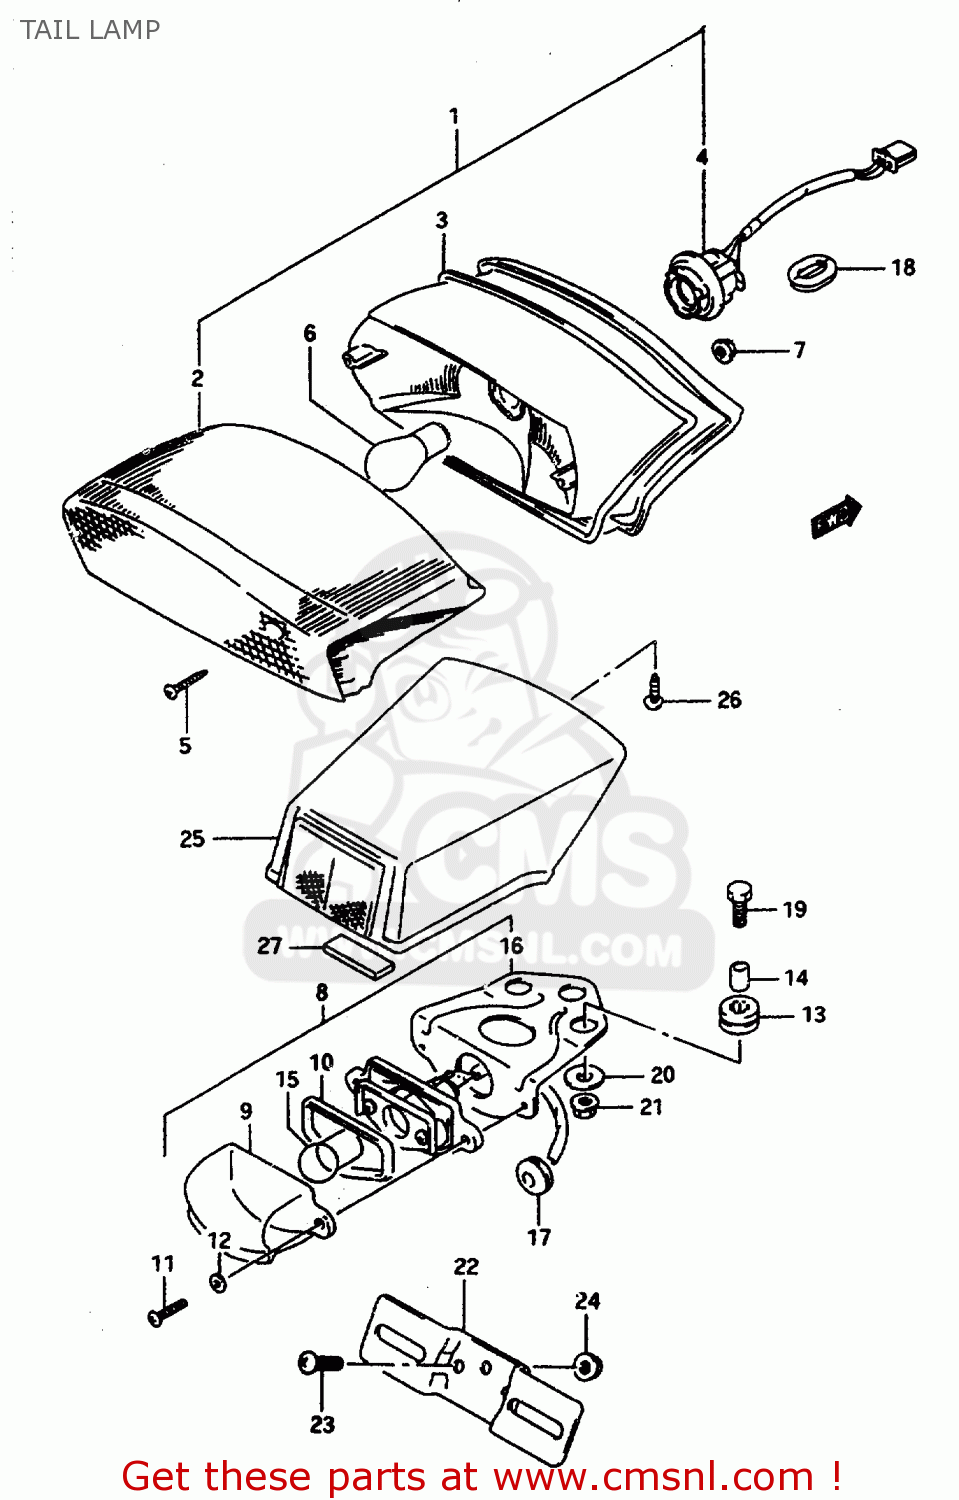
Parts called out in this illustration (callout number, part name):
1	LAMP ASSY,RR COMBINATION
2	LENS
3	GASKET (NAS)
4	SOCKET
5	SCREW
6	BULB(12V21/5W)
7	NUT
8	LAMP ASSY,LICENSE
9	LENS,LICENSE LAMP
10	GASKET,LICESE LAMP (NAS)
11	SCREW 4X16
12	WASHER
13	CUSHION,RR COMBINATION
14	SPACER
15	BULB(12V5W,BF150-40160A)
16	BRACKET
17	GROMMET
18	GROMMET
19	BOLT(6X20)
20	WASHER(6.5X20X1.2)
21	NUT
22	BRACKET,LICENSE PLATE
23	SCREW
24	NUT 6MM
25	COVER,LICENSE LAMP
26	SCREW
27	PROTECTOR,LICENSE LAMP
